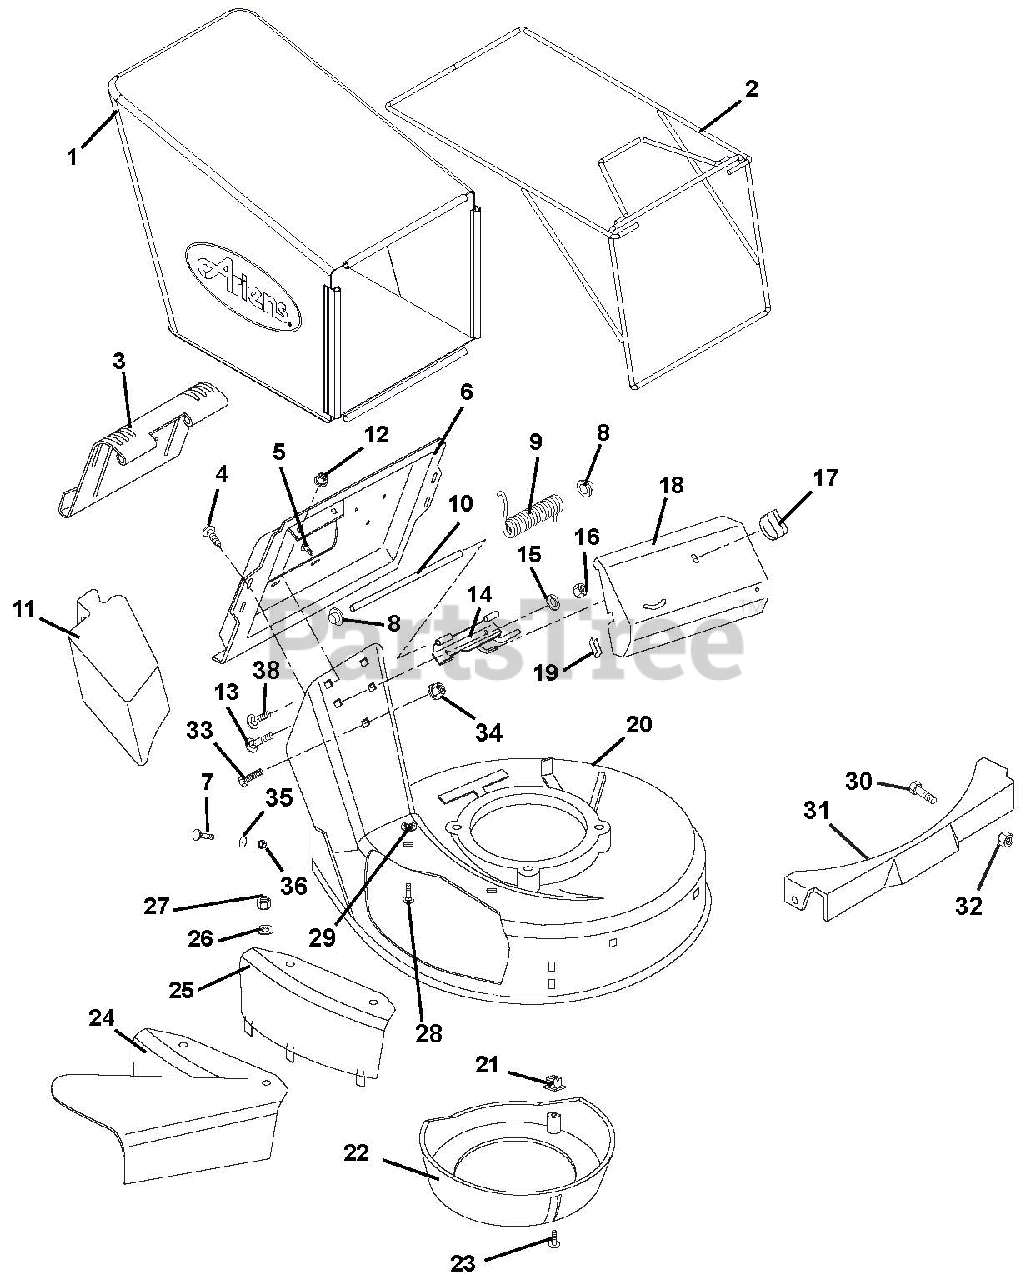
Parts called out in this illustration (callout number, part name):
1	BAGGER, ARIENS LM
2	FRAME, BAGGER
3	CATCHER PLATE DOOR
4	@SCR-TAP 12-24X.50 HWH TR YWZC
5	SCR-TAP 10-24X.375 TORX PHD YZ
6	CATCHER PLATE
7	@BLT-RDHDSQNK .25-20X.50 G5YZ
8	PUSH NUT, .25
9	SG-TORS .120X.68X3.09
10	DOOR PIN
11	MULCH MASTER PLUG
12	@NUT-SPNLK-FLG .25-20 YWZC
13	@BLT-RDHDSQNK .25-20X.75 G5YZ
14	HINGE BASE WELDMENT
14	HINGE BASE
15	WSHR-LK .250X.077 HVY YWZC
16	@NUT-HEX .25-20 YWZC
17	WING - NUT
18	COVER, LM DRIVE
19	TRIM-BULK
20	MOWER PAN HEAD W/SFTYDECALS SP
20	MOWER PAN W/SAFETY DECALS PUSH
21	PLASTIC GROMMET
22	CENTER BAFFLE
23	SCR-TAP 10-16X.62 SLPH AB YWZC
24	SIDE DISCHARGE ASSEMBLY
25	COVER, SIDE DISCHARGE
26	@WSHR-FL-STL.406X.812X.065 YWZ
27	@NUT-LK-NYL .312-18 YWZC
28	@BLT-RHDSSQNK .31-18X.75 G5YZ
29	NUT-PUSH .312
30	@BLT-RDHDSQNK .31-18X.50 G5YZ
31	PANEL-FRONT
32	@NUT-LK-TOP-FLG .31-18 YWZC
33	@BLT-HEX .38-16X.50 GR5 YWZC
34	@NUT-SPNLK-FLG .375-16 YWZC
35	@WSHR-FL-STL.38X.875X.083 YWZC
36	@NUT-LK-CTR .25-20 YWZC
37	@BLT-HEX .25-20X.50 GR5 YWZC
38	@BLT-RHDSSQNK .25-20X.38 G2YZ
